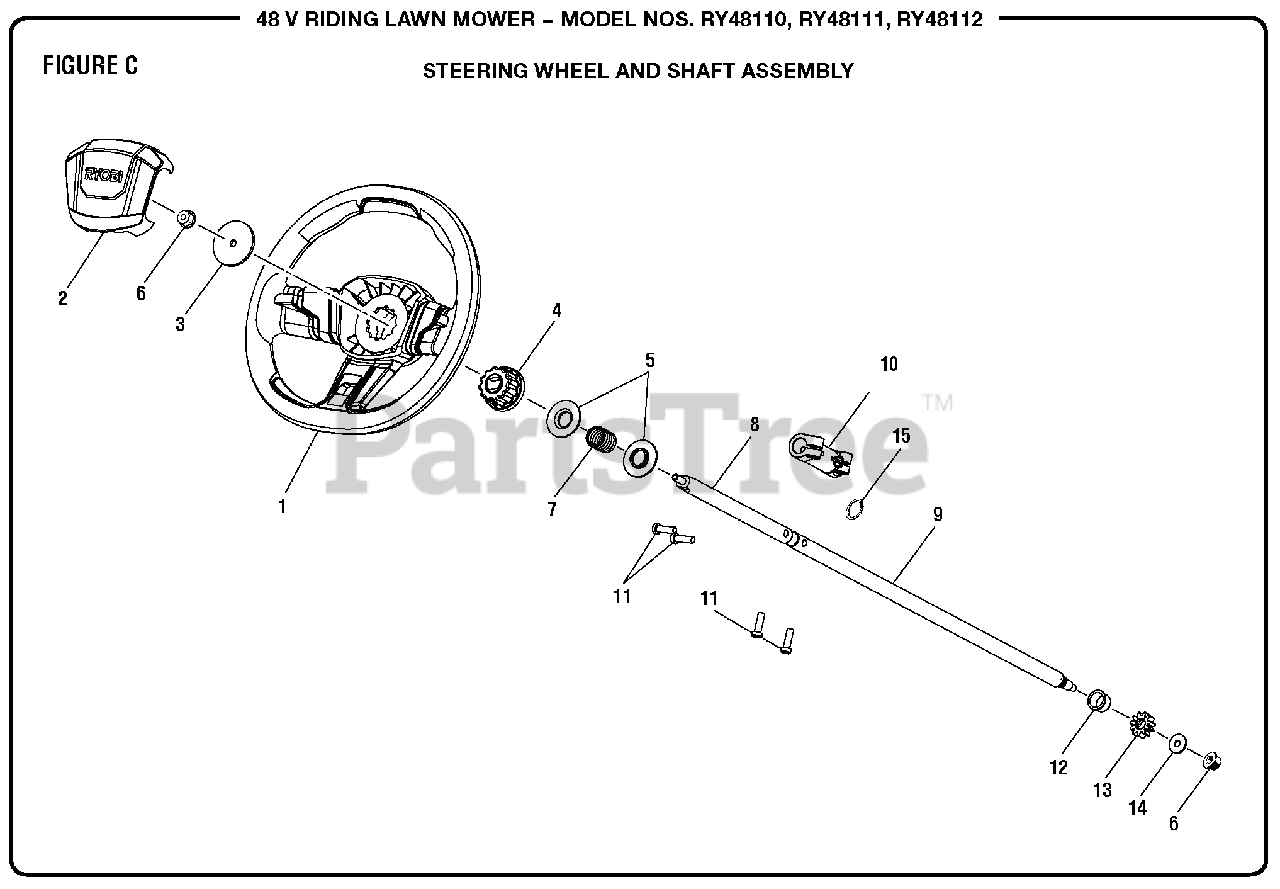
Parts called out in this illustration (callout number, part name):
1	Steering Wheel
2	Steering Wheel Cap
3	Washer Plate
4	Spline Collar
5	Spring Seat
6	Flange Lock Nut (M8)
7	Steering Shaft Spring
8	Upper Steering Shaft
9	Lower Steering Shaft
10	Steering Shaft Coupling
11	Screw (M8 x 25 mm, Soc. Hd.)
12	Flanged Bushing (19 x 22 x 15)
13	Steering Pinion Gear
14	Washer (OD24 x ID8.4 x 2t)
15	Retaining Ring
